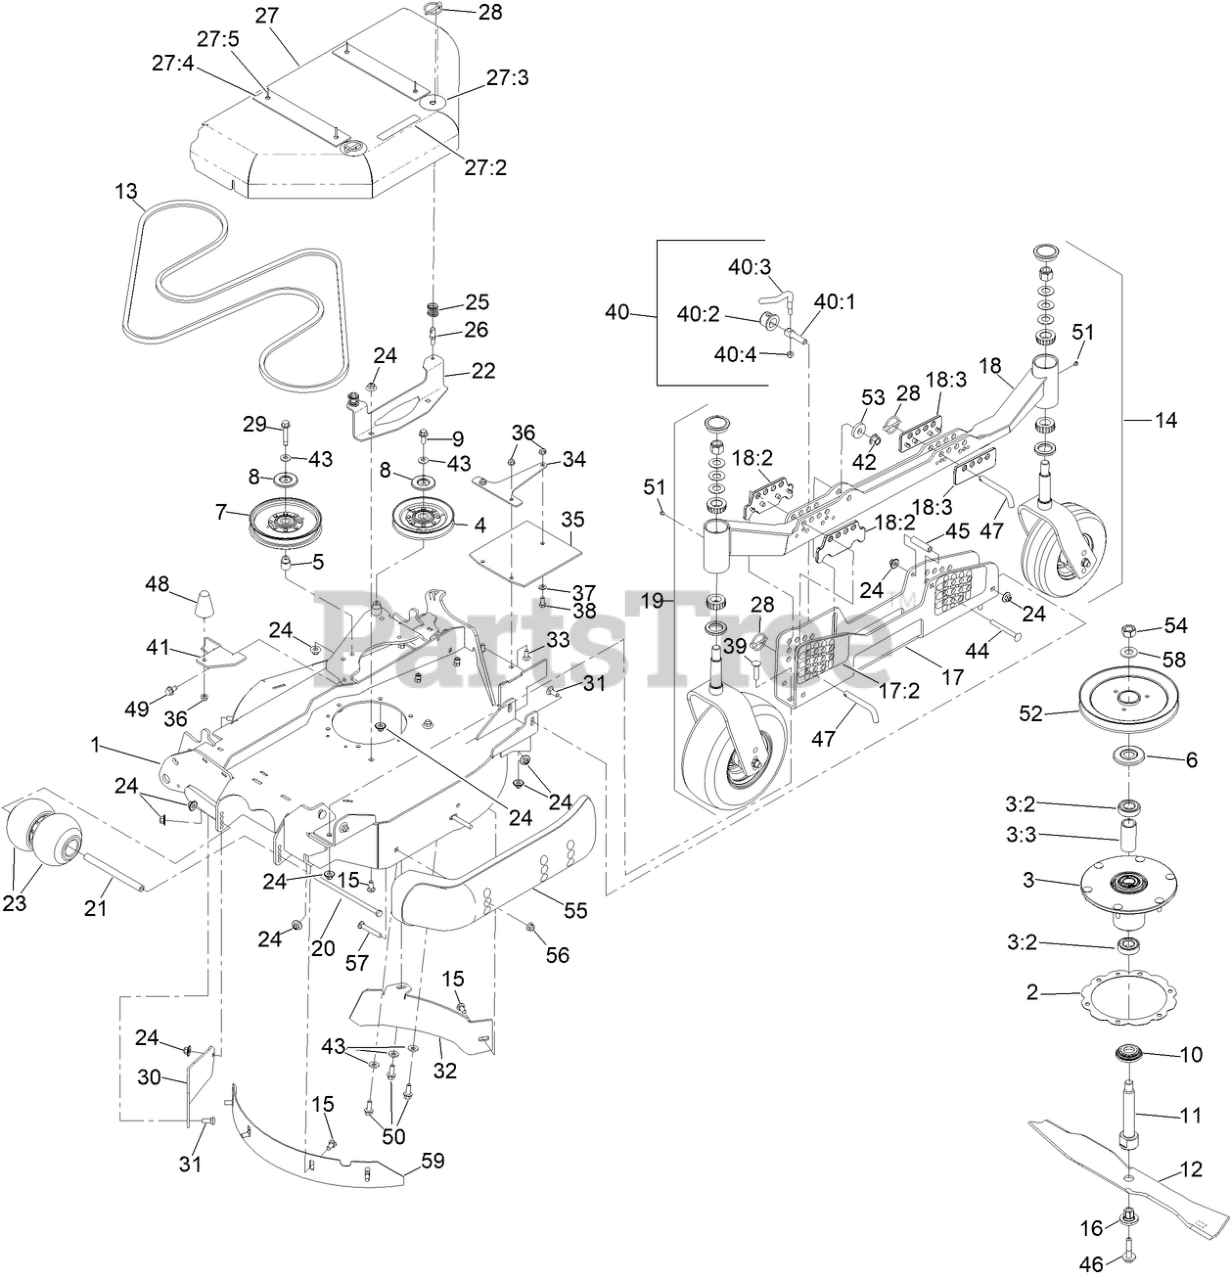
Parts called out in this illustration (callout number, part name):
1	ASM-DECK, LH WING 96 T
2	RING-SPACER, HOUSING
3	SPINDLE ASM
3:2	BEARING-BALL
3:3	SPACER-BEARING
4	IDLER-V
5	BUSHING-IDLER
6	GUARD-BEARING, TOP
7	IDLER-PULLEY
8	SHIELD-DUST
9	SCREW-HHF
10	GUARD-BOTTOM
11	SHAFT-SPINDLE
12	BLADE-24.50 MULCH
13	BELT-V
14	REAR CASTER WHEEL ASM
15	BOLT-CARR
16	BUSHING-HEX
17	ASM-CHANNEL, HOC LH
17:2	DECAL-HEIGHT OF CUT-LH
18	ASM-LH GAUGE WHEEL ARM
18:2	PLATE-GUIDE, FRONT
18:3	PLATE-GUIDE, REAR
19	CASTER WHEEL ASM
20	SCREW-HH
21	SPACER-WHEEL
22	BRACKET-SHIELD MOUNT, OUTER
23	ROLLER-SCALP, ANTI
24	NUT-FLANGE, NI
25	SPRING
26	PIN, SPRING
27	LH WING SHIELD ASM
27:2	DECAL-NO STEP
27:3	DECAL-SCRATCH COVER
27:5	RIVET-POP
28	PIN-LYNCH
29	SCREW-HHF W/ PATCH
30	PLATE-FILL, LH DECK
31	BOLT-CARR
32	BAFFLE-BLOCK
33	SCREW-CARR
34	SUPPORT-FLAP, LH
35	GUARD-TIRE, LH
36	NUT-HF, NI
37	WASHER-PLAIN
38	SCREW-HH
39	SCREW-CARR
40	LEVER ASM
40:1	SCREW-LOCK
40:2	CAP-LOCK
40:4	NUT-LOCK, NI
41	BRACKET-COVER RETAINER
42	NUT-LOCK
43	WASHER-BELLEVILLE
44	SCREW-CARR
45	SPACER
46	SCREW-SEMS
47	PIN-HOC
48	BUMPER-RUBBER
49	SCREW-HWH
50	SCREW-HHF
52	SHEAVE-DRIVE, BLADE
53	WASHER
54	NUT-HEX
55	SKID-BUMPER, DECK
56	NUT-HF, NI
57	SCREW-CARR
58	WASHER
59	BAFFLE-DEPTH, LH
